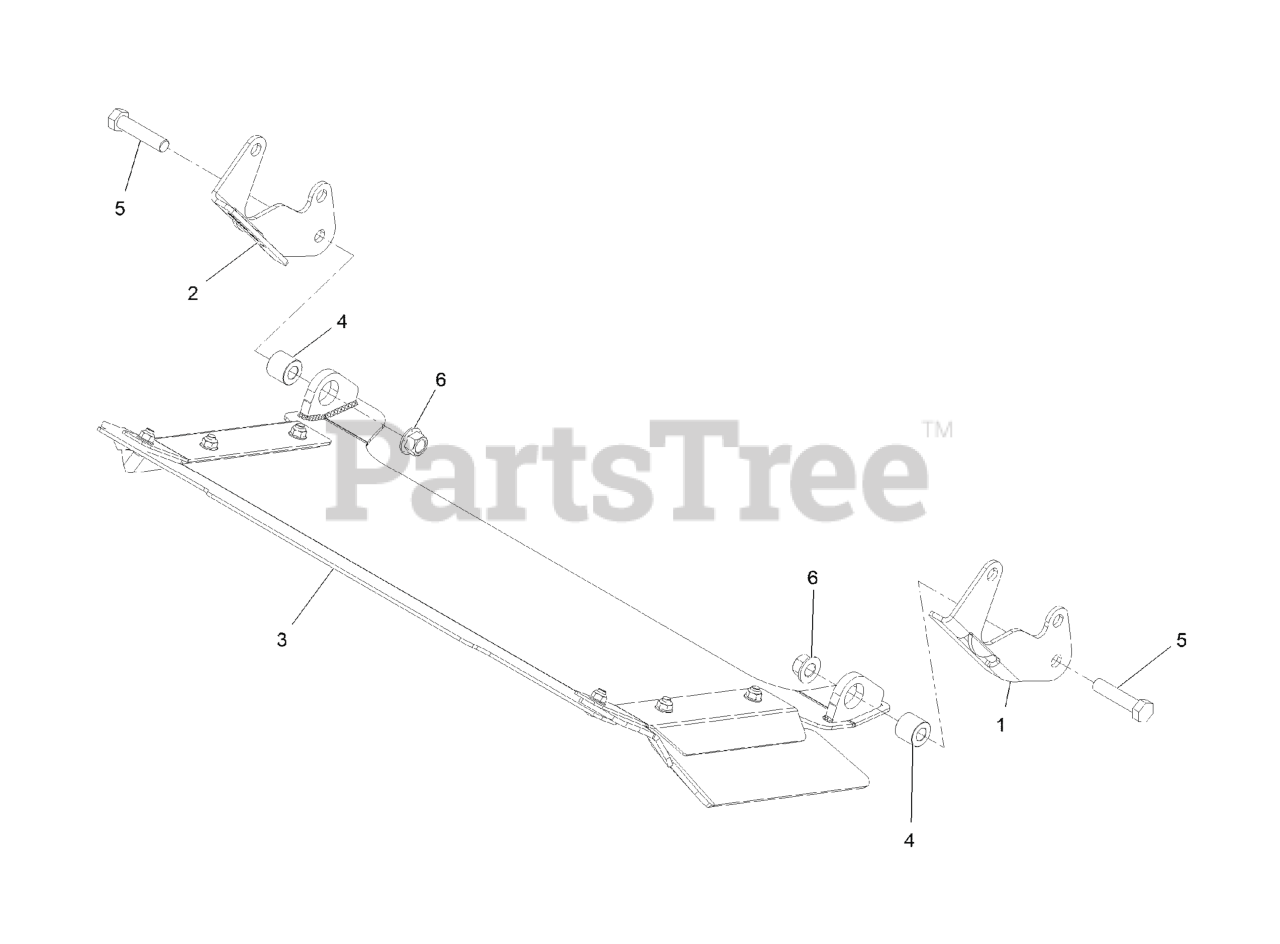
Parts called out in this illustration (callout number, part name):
1	BRACKET-DISCHARGE MOUNT,
2	BRACKET-DISCHARGE MOUNT,
3	DISCHARGE TUNNEL ASM
4	BUSHING-SLEEVE
5	SCREW-HH
6	Nut-Lock 1/2-13
